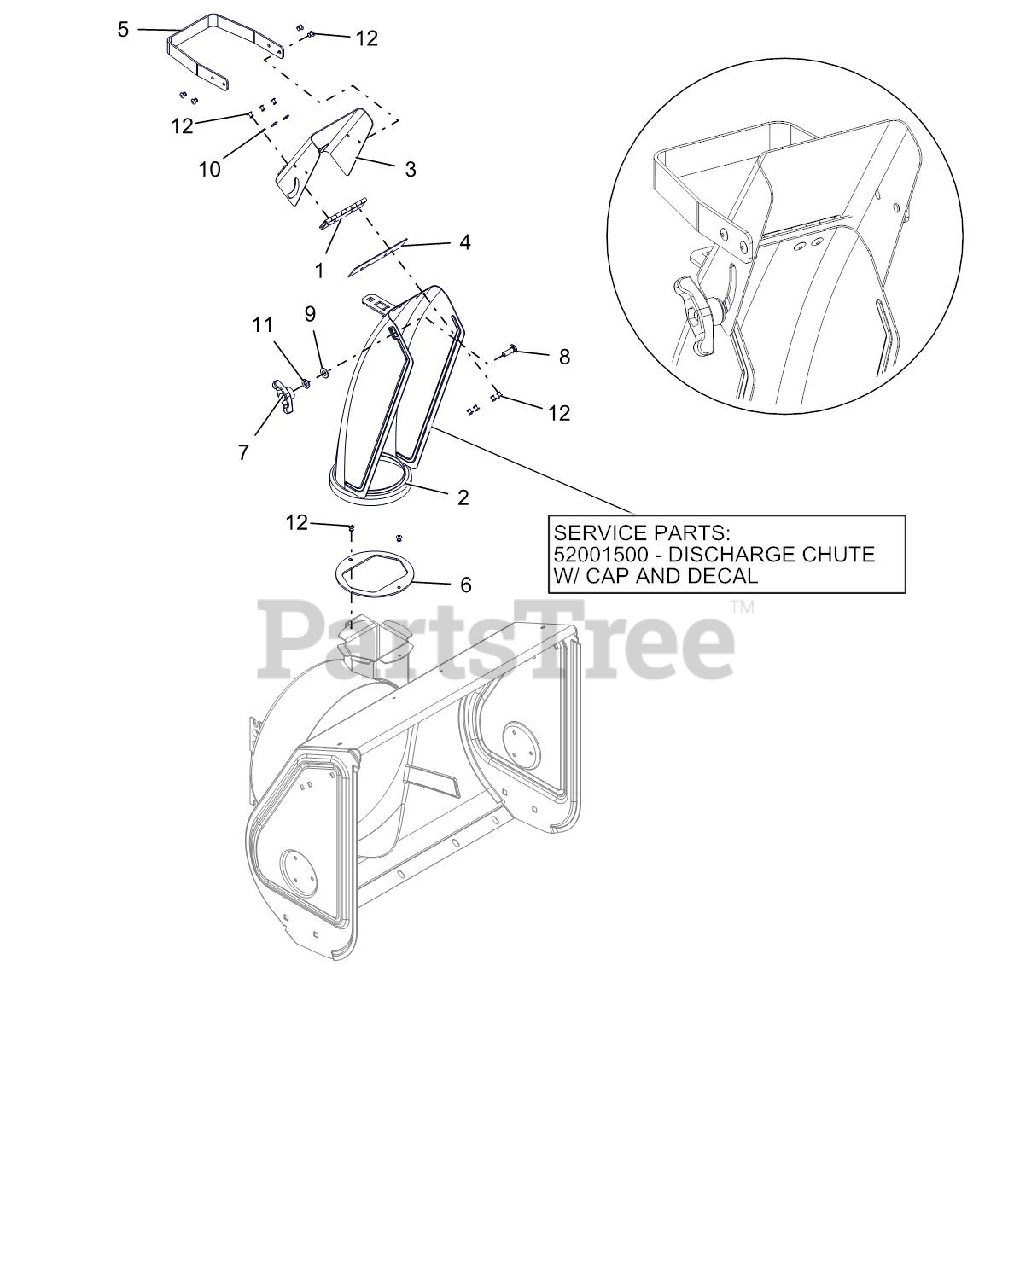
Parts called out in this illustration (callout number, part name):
2	CHUTE, DISCHARGE W/CAP & DECAL
2	CHUTE, COMPACT - TALL
3	CAP,MANUAL - COMPACT (W/DECAL)
4	CAP SEAL 5.25
5	HANDLE, DEFLECTOR
6	BAFFLE, COMPACT DISCHARGE
7	KNOB,WING .31-18 UNC NYL/TALC
8	@BLT-RHDSSQNK .31-18X1.00 G5YZ
9	WSHR-FL-NY .375X.75X.060
10	WSHR-FL-STL .196X.500X.06 YZ
11	@WSHR-FL-STL.344X.688X.065YWZC
12	RVT-POP .187 YZ
